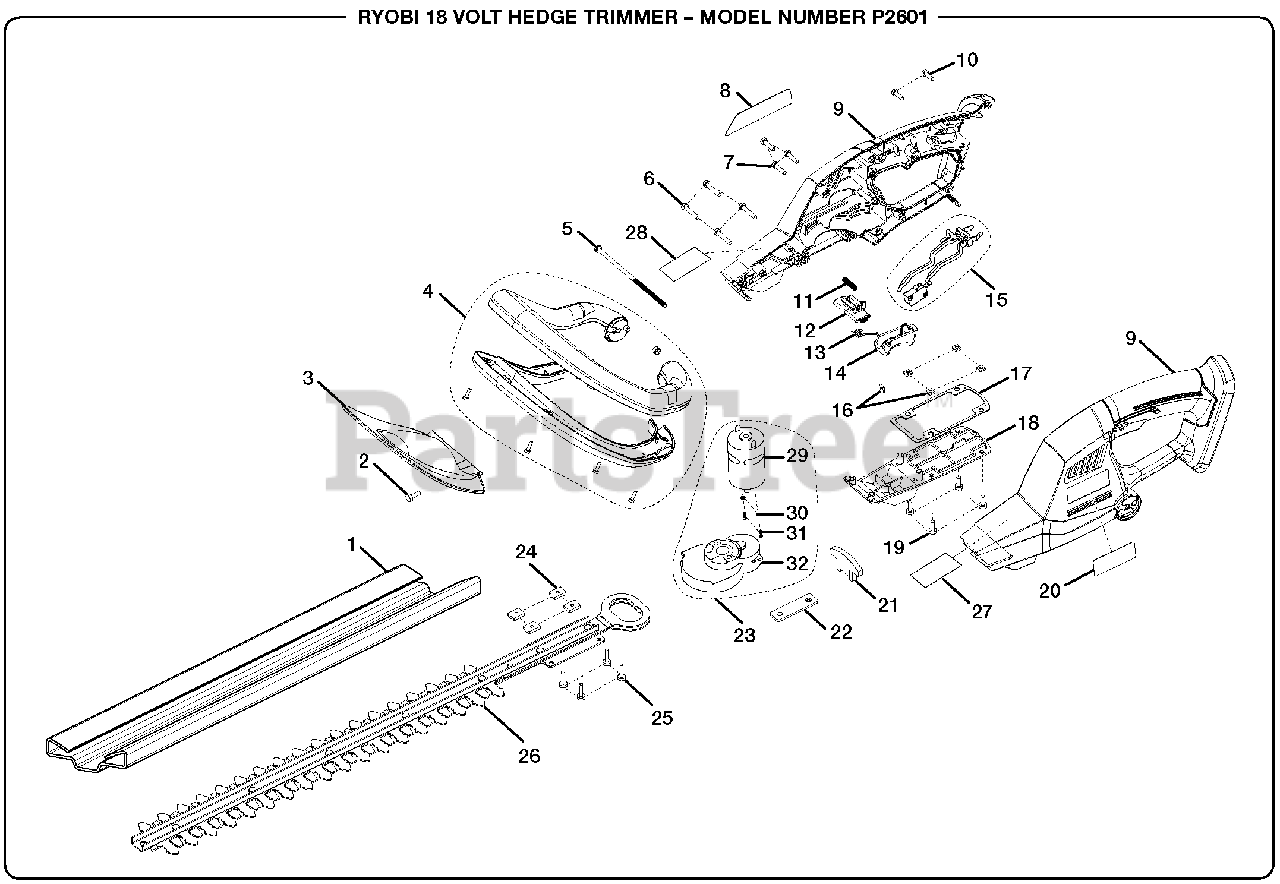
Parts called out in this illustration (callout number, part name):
1	Blade Cover
2	Screw (M4 x 12 mm)
3	Guard Block
4	Front Handle Assembly
5	Screw (M4 x 114 mm)
6	Screw (M4 x 22 mm Pan Hd.)
7	Screw (M4 x 16 mm Pan Hd.)
8	Data Label
9	Housing Assembly
10	Screw (M4 x 12 mm Pan Hd.)
11	Compression Spring
12	Trigger Lock
13	Trigger Spring
15	Switch and Circuit Assembly
16	Square Nut (M4 x 2.2 mm)
17	Rubber Seal
18	Bottom Cover
19	Screw (M4 x 12 mm)
20	Logo Label
21	Sponge Seal
22	Bar Plate
23	Motor & Gear Train Assembly (Inc. Key Nos. 9-32)
24	Square Nut (M4 x 15 x 10.9)
25	Screw (M4 x 16 mm)
26	Blade Assembly
27	Warning Label
28	Warning Label
29	Motor Assembly
30	Retaining Ring (External)
31	Screw (M4 X 1 mm)
32	Gear Train Assembly
